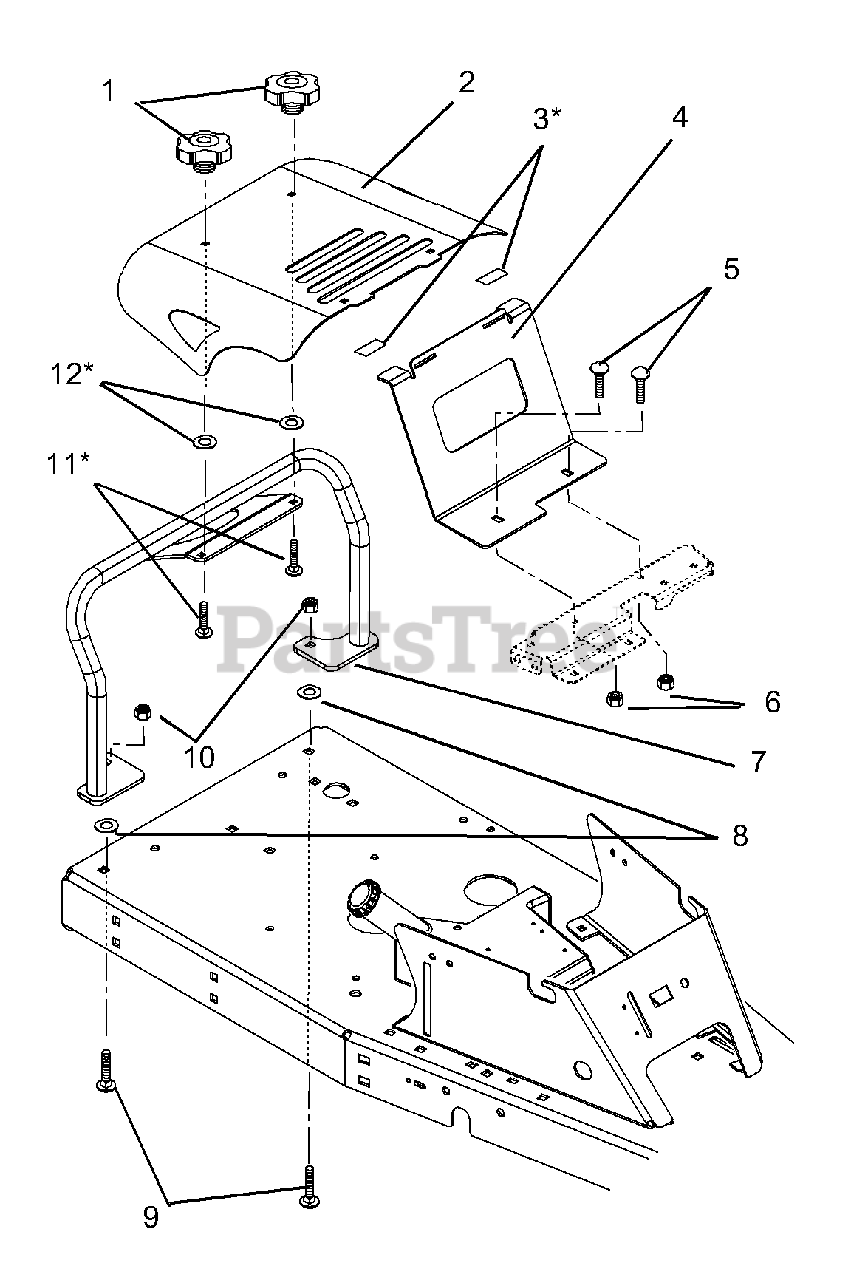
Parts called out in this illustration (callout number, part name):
1	KNOB-CLAMPING, .312-18 NYLOC
2	ENGINE-HOOD ARIENS
2	HOOD ENGINE GRAVELY
3	TAPE-FOAM .12X1.00 VINYL
4	BRACKET-HOOD SUPPORT
5	BLT-RDHDSQNK .31-18X.75 G5BZ
6	@NUT-LK-NYL-FLG .31-18 YWZC
7	WLDM'T TUBE
8	RETAINER, .38 PUSH-ON
9	@BLT-RDHDSHSQNK.38-16X1.0 G5YZ
10	@NUT-LK-NYL-FLG .38-16 YWZC
11	BLT-RDHDSQNK .31-18X1.0 SHTYZ
12	NUT-PUSH .312
12	KIT-HOOD RER/SPORT ARIENS
12	KIT-HOOD RER/SPORT GRAVELY
